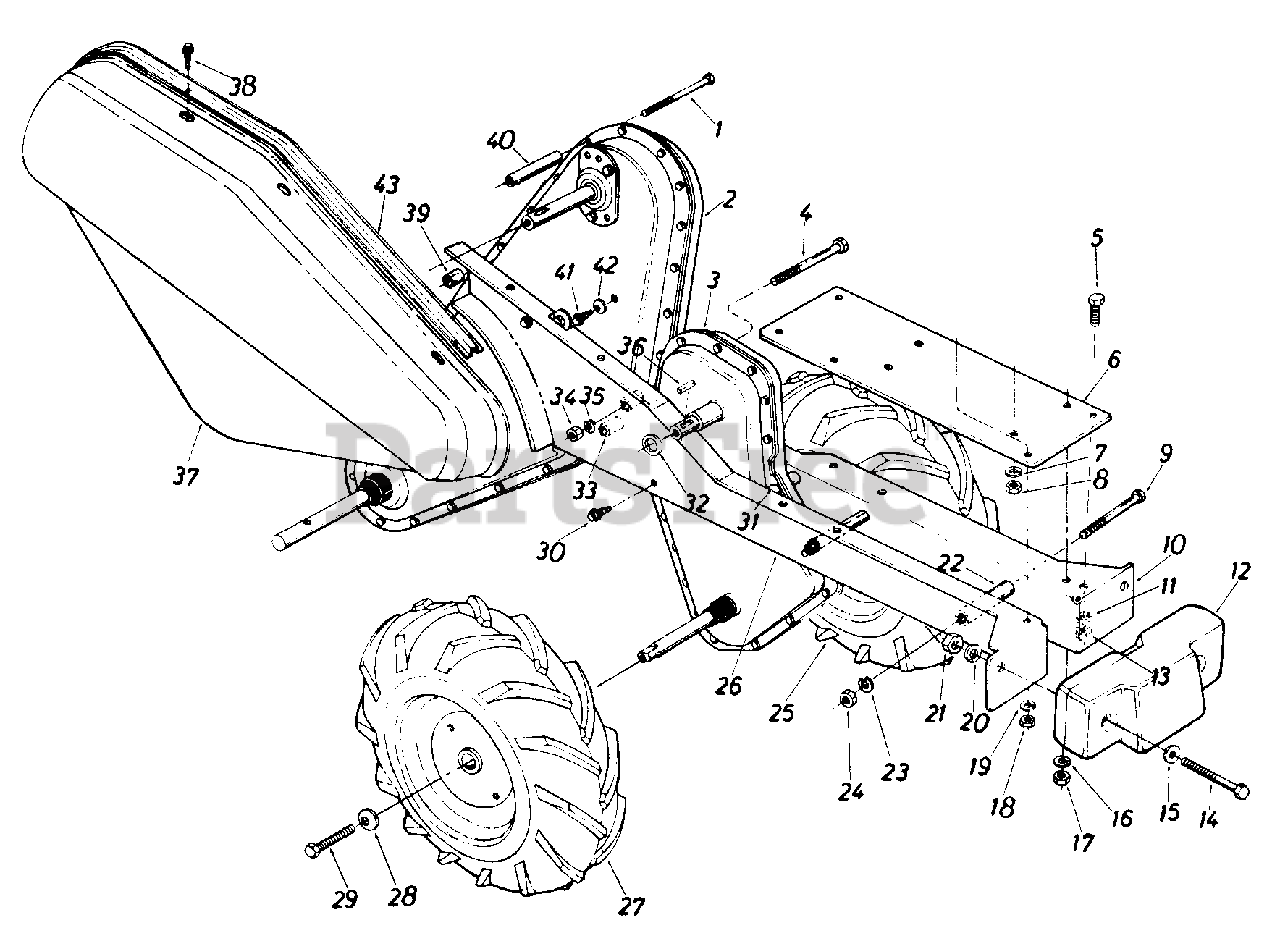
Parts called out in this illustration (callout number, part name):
1	Hex Bolt 5/16-18 x 3.00" Lg.*
2	Chain Case Ass'y. Comp. Tines
3	Chain Case Ass'y. Comp. Wheels
4	Hex Bolt 5/16-18 x 3.00" Lg.*
5	Hex Bolt 5/16-18 x .75" Lg.*
8	Hex Nut 5/16-18 Thd.*
9	Hex Bolt 3/8-24 x 3.00" Lg.*
12	Weight 35#
13	Hex Nut 5/16-18 Thd.*
14	Hex Bolt 1/2-13 x 4.00" Lg.*
15	Fl-Wash. .510" I.D. x 1.0" O.D.
16	L-Wash. 5/16" I.D.*
17	Hex Nut 5/16-18 Thd.*
18	Hex Nut 5/16-18 Thd.*
19	L-Wash. 5/16" I.D.*
20	L-Wash. 1/2" I.D.*
21	Hex Nut 1/2-13 Thd.*
22	Spacer .38" I.D. x .62" O.D. x 2.18" Lg.
23	L-Wash. 3/8" I.D.*
24	Hex Nut 3/8-24 Thd.*
25	Wheel Ass'y. Comp. 12.5 x 3.5-L.H.
28	Belleville Wash. .345" I.D. x .88" O.D.
29	Hex Bolt 5/16-24 x .62" Lg.
30	Hex Wash. Hd. SF-Tap Scr. 5/16-24 x .50" Lg.
31	Spacer .326" I.D. x .47" O.D. x .96" Lg.
32	Fl-Wash. .635" I.D. x 1.00"
33	Spacer .326" I.D. x .47" O.D. x .96 Lg.
34	Hex Nut 5/16-18 Thd.*
35	L-Wash. 5/16" I.D.
36	Sq. Key 3/16 x .75" Lg.
37	Belt Cover
38	Hex Wash. Hd. SF-Tap Scr. 1/4-20 x .50" Lg.
39	Spacer .326" I.D. x .47" O.D. x .96" Lg.
40	Spacer .375 I.D. x .500" O.D. x 2.00" Lg.
41	Hex Wash. Hd. SF-Tap Scr. 1/4-20 x .50" Lg.
42	Bell-Wash. .265" I.D. x .75"
43	Flange Extension
